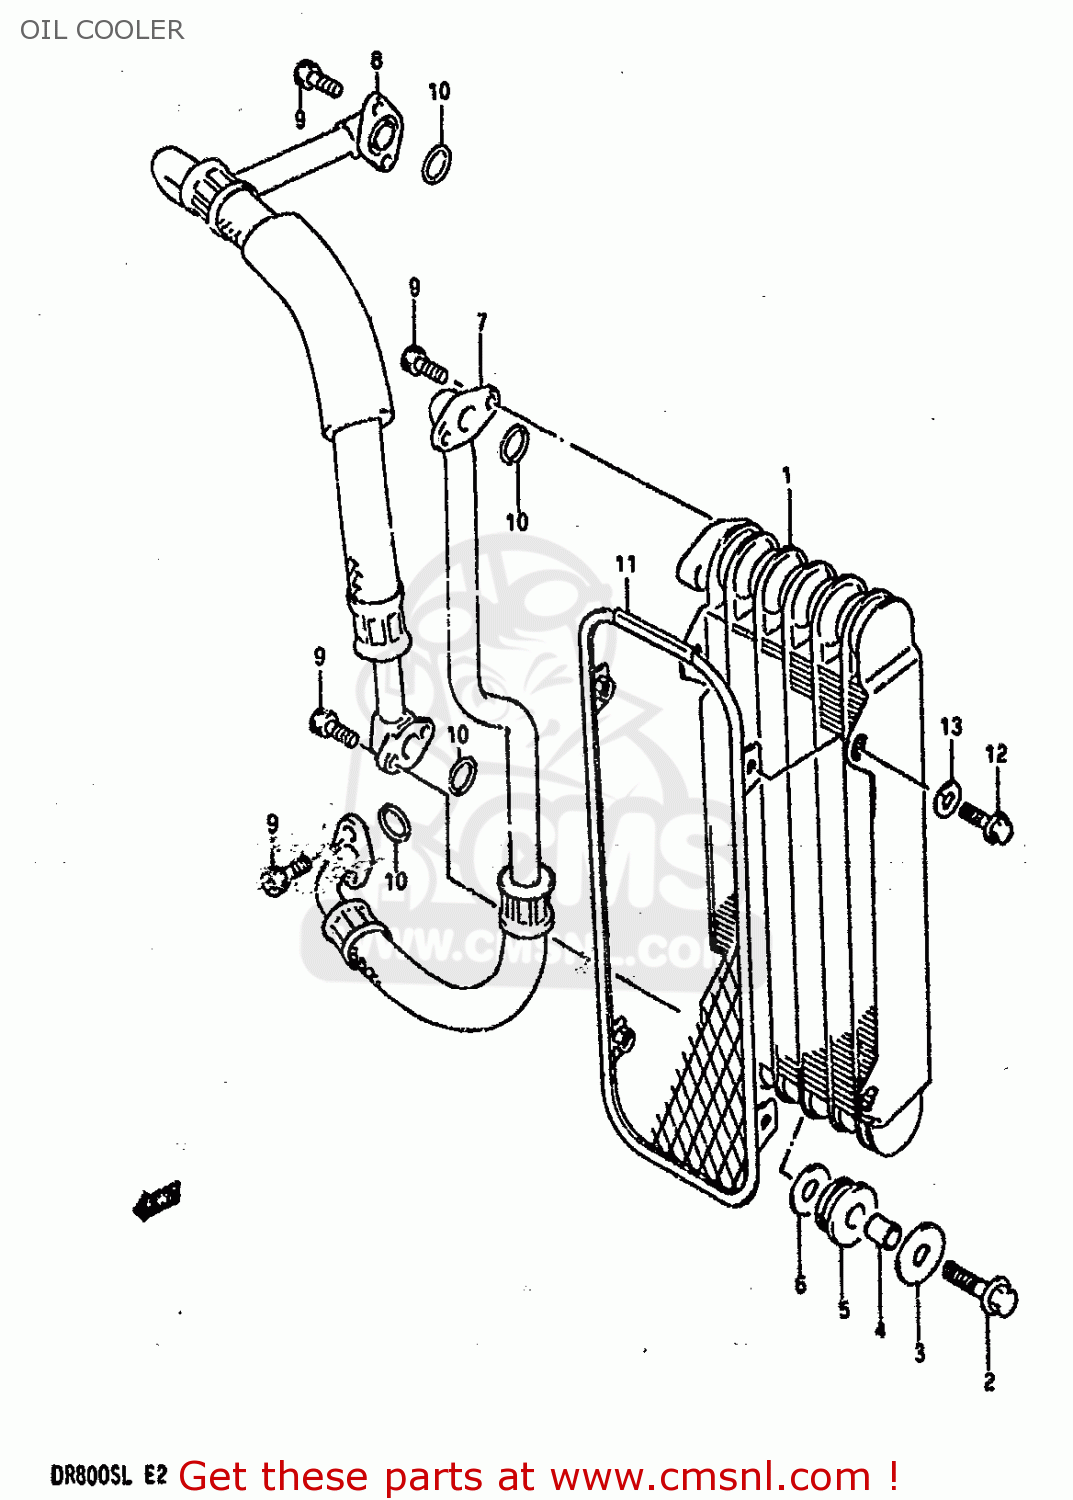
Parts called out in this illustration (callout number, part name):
1	COOLER ASSY,OIL
2	BOLT
3	WASHER (8.5X20X1.6)
4	SPACER (8.8X12X11.6)
5	CUSHION,OIL COOLER
6	WASHER(8.5X23X1.2)
7	HOSE,OIL COOLER NO.1
8	HOSE,OIL COOLER NO.2
9	BOLT
10	O RING(D:2.4,ID:12.3)
11	BUMPER,OIL COOLER
12	BOLT
13	WASHER,LOCK
